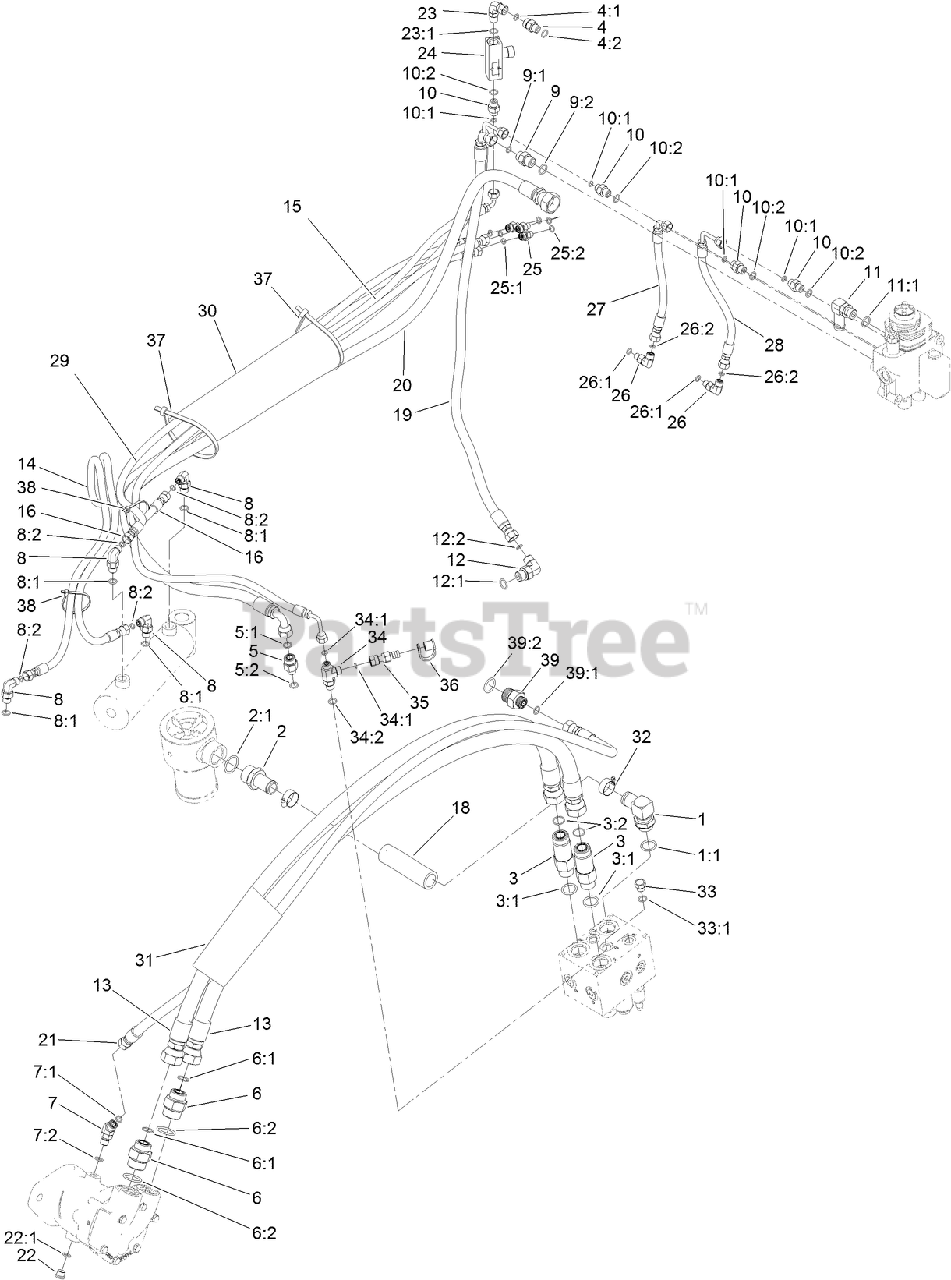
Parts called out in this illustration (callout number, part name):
1	FITTING-90
1:1	O-RING
2	FITTING-STR
2:1	O-RING
3	FITTING-STR
3:1	O-RING
3:2	O-RING
4	FITTING-STRAIGHT
4:1	O-RING
4:2	O-RING
5	FITTING-STRAIGHT
5:1	O-RING
5:2	O-RING
6	FITTING-STR
6:1	O-RING
6:2	O-RING
7	FITTING-ELBOW, 45 DEG
7:1	O-RING
7:2	O-RING
8	FITTING-ELBOW, 90 DEG
8:1	O-RING
8:2	O-RING
9	FITTING-STRAIGHT
9:1	O-RING
9:2	O-RING
10	FITTING-STRAIGHT
10:1	O-RING
10:2	O-RING
11	FITTING-ELBOW, 90
11:1	O-RING
12	FITTING-HYD, 90 DEG
12:1	O-RING
12:2	O-RING
13	HOSE-HYD
14	HOSE-HYD
15	HOSE-HYD
16	HOSE-HYD
18	HOSE-RETURN
19	HOSE-HYD
20	HOSE-HYD
21	HOSE-HYD
22	PLUG-HEX, HOLLOW
22:1	O-RING
23	FITTING-SWIVEL, 90 DEG
23:1	O-RING
24	VALVE-CONTROL, FLOW
25	FITTING-STRAIGHT
25:1	O-RING
25:2	O-RING
26	FITTING-ELBOW, 90 DEG
26:1	O-RING
26:2	O-RING
27	HOSE-HYD
28	HOSE-HYD
29	HOSE-HYD
30	SLEEVE-PROTECTIVE
31	SLEEVE-PROTECTIVE
32	CLAMP-HOSE
33	PLUG-HH
33:1	O-RING
34	FITTING-TEE
34:1	O-RING
34:2	O-RING
35	NIPPLE-TEST
36	CAP-DUST
37	TIE-CABLE
38	TIE-CABLE
39	FITTING-STR
39:1	O-RING
39:2	O-RING
